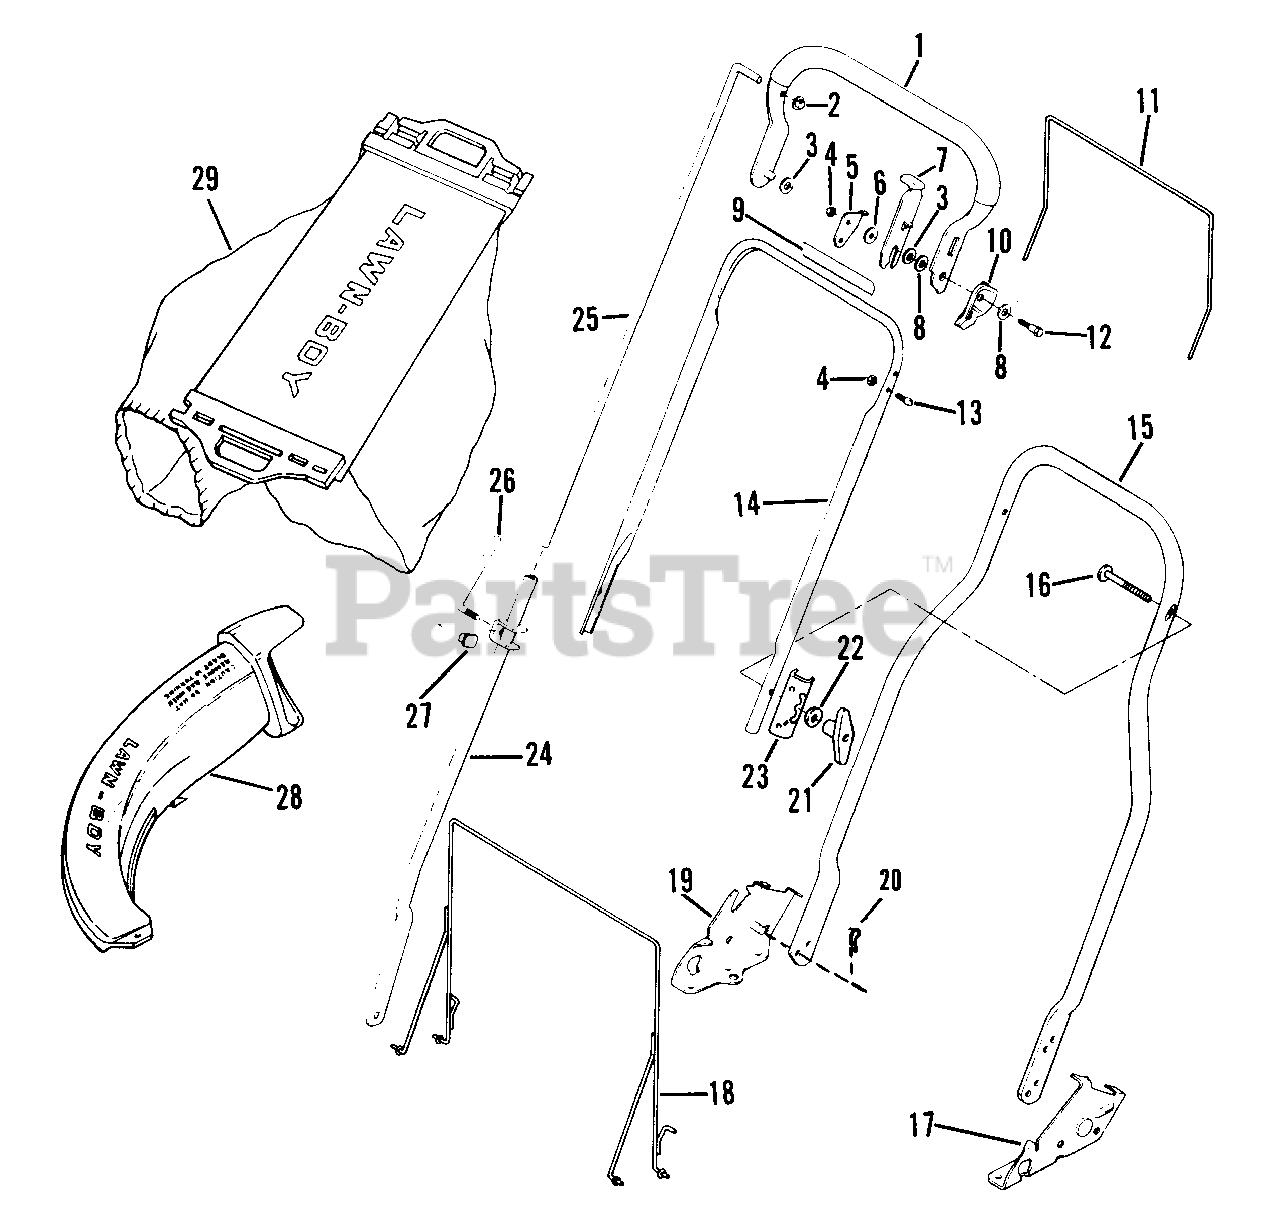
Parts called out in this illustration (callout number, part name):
1	Handle & Grip Assembly
2	Palnut
3	Washer
4	Nut-Lock
5	Stop-Handle
6	Washer
7	Lever-Lockout
8	Washer
9	Decal
10	Guard-Lever
11	Hanger-Rear
12	Bolt-Shoulder
13	Screw-Stop
14	Handle-Center
15	Handle Section-Bottom
16	Screw
17	Bracket-Handle-L.H.
18	Hanger Assembly-Front
19	Bracket-Handle-R.H.
20	Hair Pin
21	Knob
22	Washer-Curved
23	Bracket-Rear Hanger
24	Control Lever Assembly
25	Control Rod
26	Screw
27	Nut
28	Chute Assembly
29	Bag & Support Assembly
